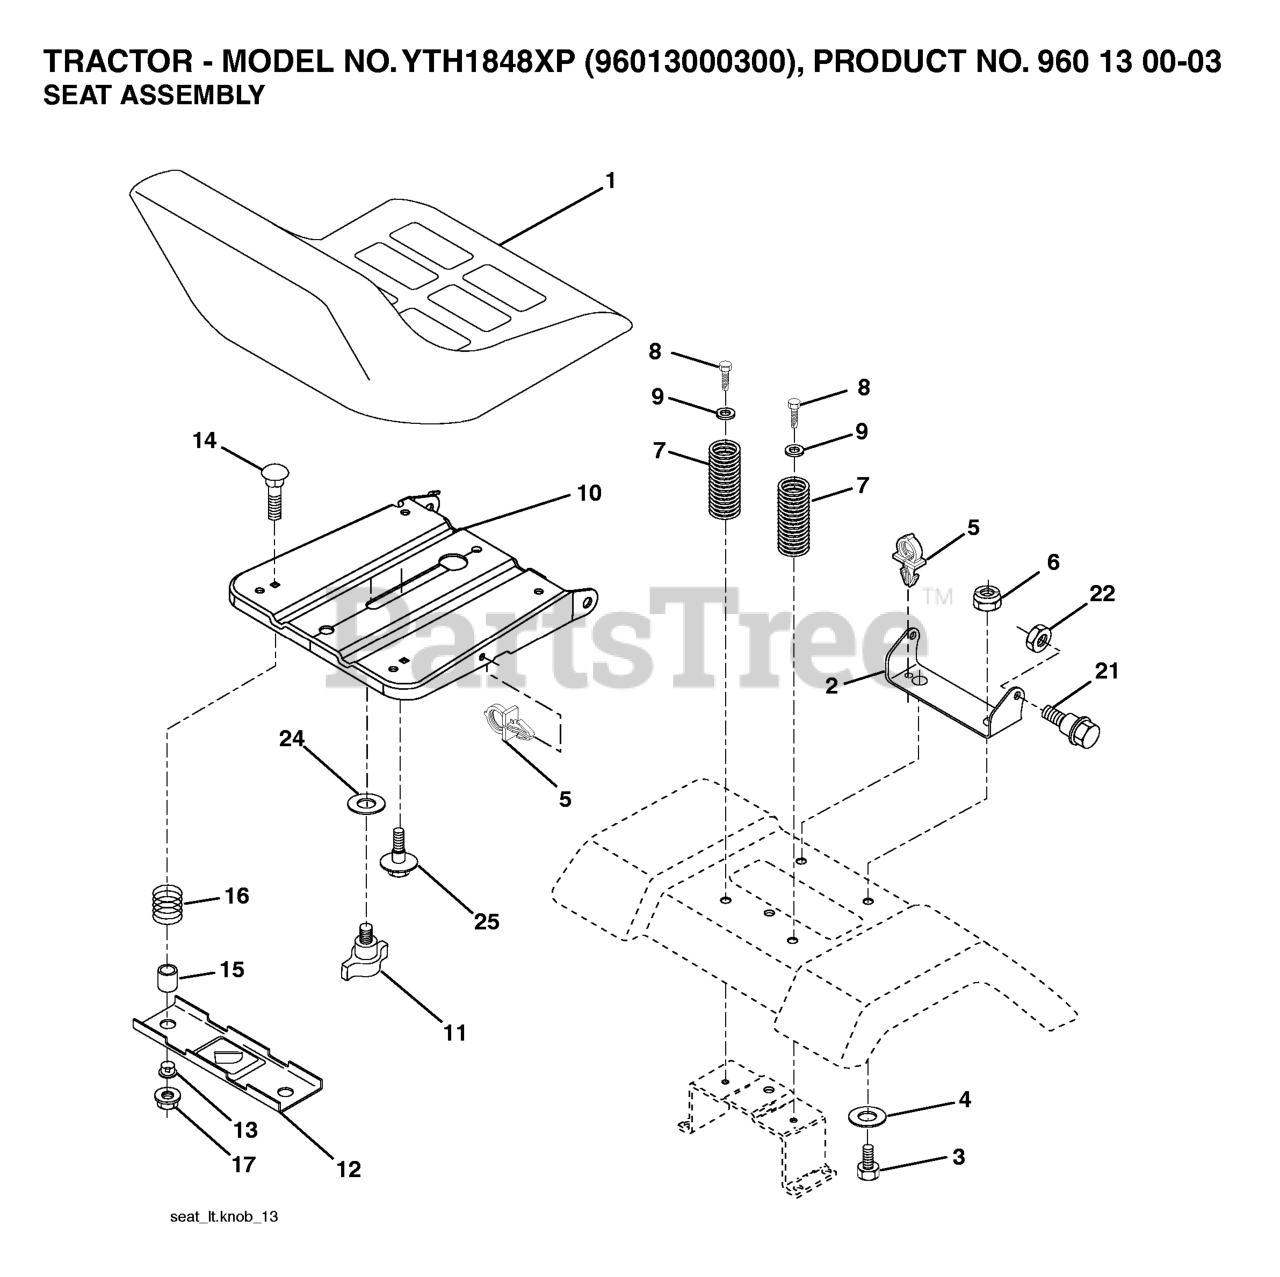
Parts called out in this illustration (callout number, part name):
1	SEAT.XH150.GRY
2	SEAT PIVOT BRKT
3	BOLT, HEX 3/8-16X1
6	NUT
7	SPRING COMPRESSION
8	SCREW 3/8-16X1
9	WASHER
10	PAN SEAT
11	KNOB.SEAT.ADJ.WINGNUT
12	BRKT.MNTNG.SWITCH.SEAT.BLACK
14	BOLT.ROUND.HEAD.SQUARE.NECK
15	SPACER SPLIT
16	SPRING COMPRESSED
17	NUT T
21	BOLT.SHOULDER.5/16-18
22	NUT.71038.31-18.HEX.NYLOCK
25	BOLT,SHOULD
